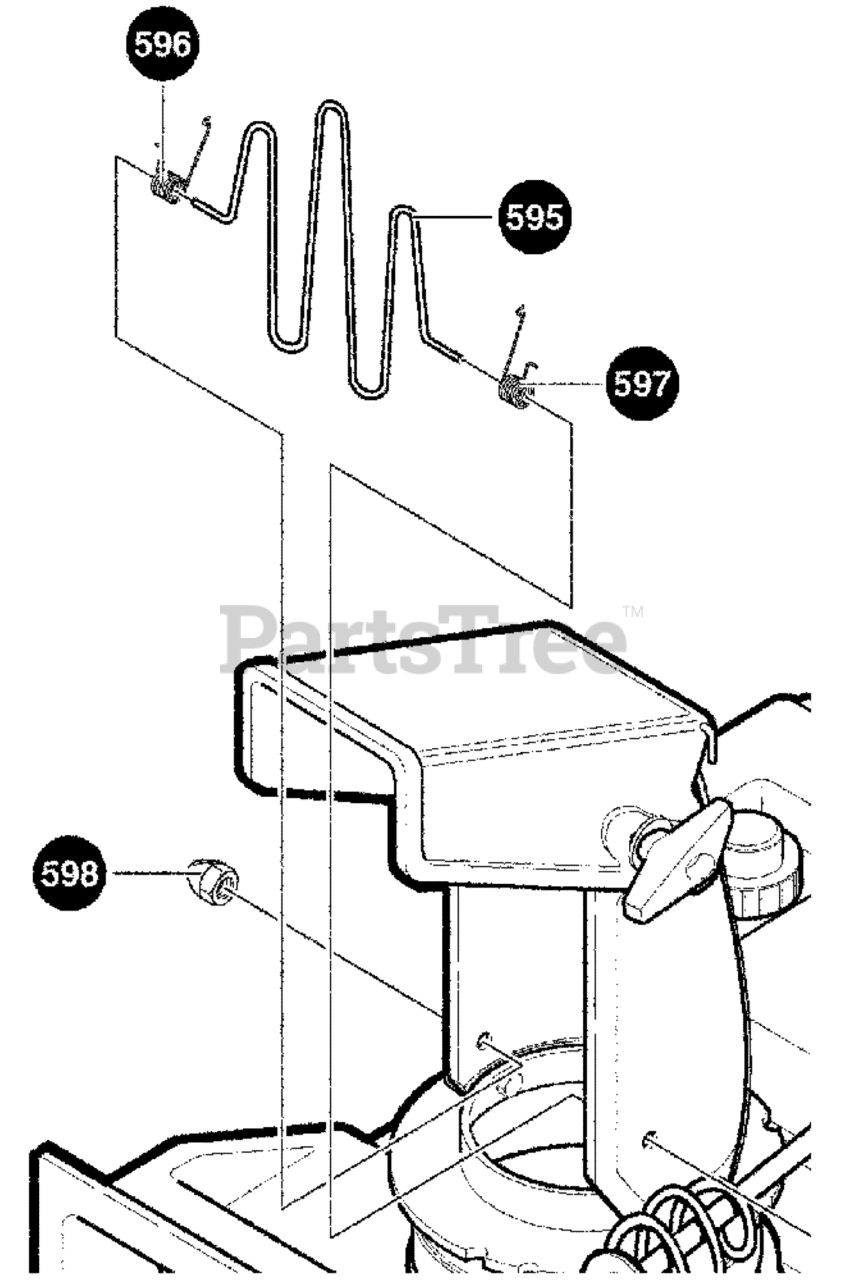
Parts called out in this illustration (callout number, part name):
595	GUARD, WIRE CHUTE
596	SPRING, TORSION
597	SPRING, TORSION
598	NUT, ACORN
